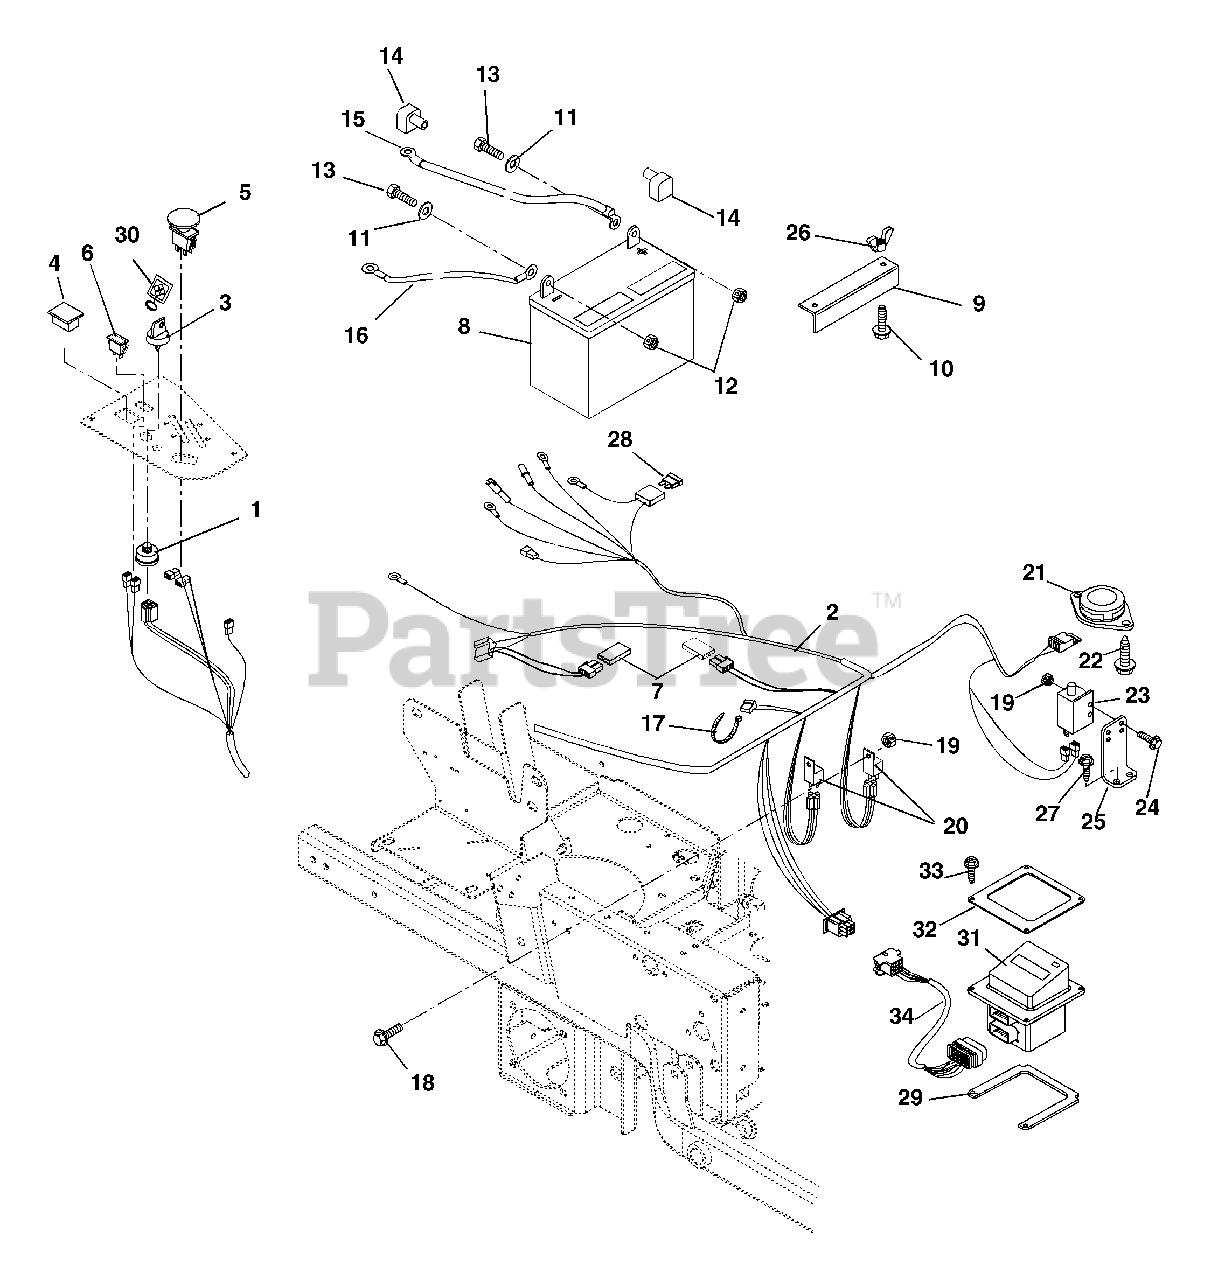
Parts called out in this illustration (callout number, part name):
1	Key Switch
2	Harness, Z-6 Pin (EYE-Q)
3	Key with Shield
5	Switch, Clutch With Retainer Ring
6	Light, Indicator Kit
7	Diode, Connector Shell
9	Hold Down
10	Bolt, Round Head Square Neck .25-20 x 7.50
11	Washer, Flat Steel .281 x .620 x .065
12	Nut, Locking Top Flange .25-20
13	Bolt, Hex .25-20 x .75 Grade 5
14	Insulator
15	Positive Cable 22"
16	Cable, Negative Battery
17	Cable Tie
18	Screw, Machine 10-24 x .50 Hex Washer Head
19	Nut, Locking Nylon 10-24 With Insert
20	Relay
21	Seat Switch
22	Screw, Tapping 12-24 x .50 Hex Washer Head
23	Switch, Single Pole
24	Screw, Machine 10-24 x .75 Hex Washer Head
25	Mount, Brake Switch
26	Nut, Locking Wing .25-20
27	Screw, Tapping .25-20 x .50 Hex Washer Head
28	Fuse, 30 Amp
29	Spacer, Enclosure Mounting (Bottom)
30	Key Chain
31	Assembly, Eye-Q
32	Plate, Eye-Q Stiffener (Top)
33	Screw, Machine 10-24 x 1.0 Slotted Pan Black
34	Harness, Eye-Q
